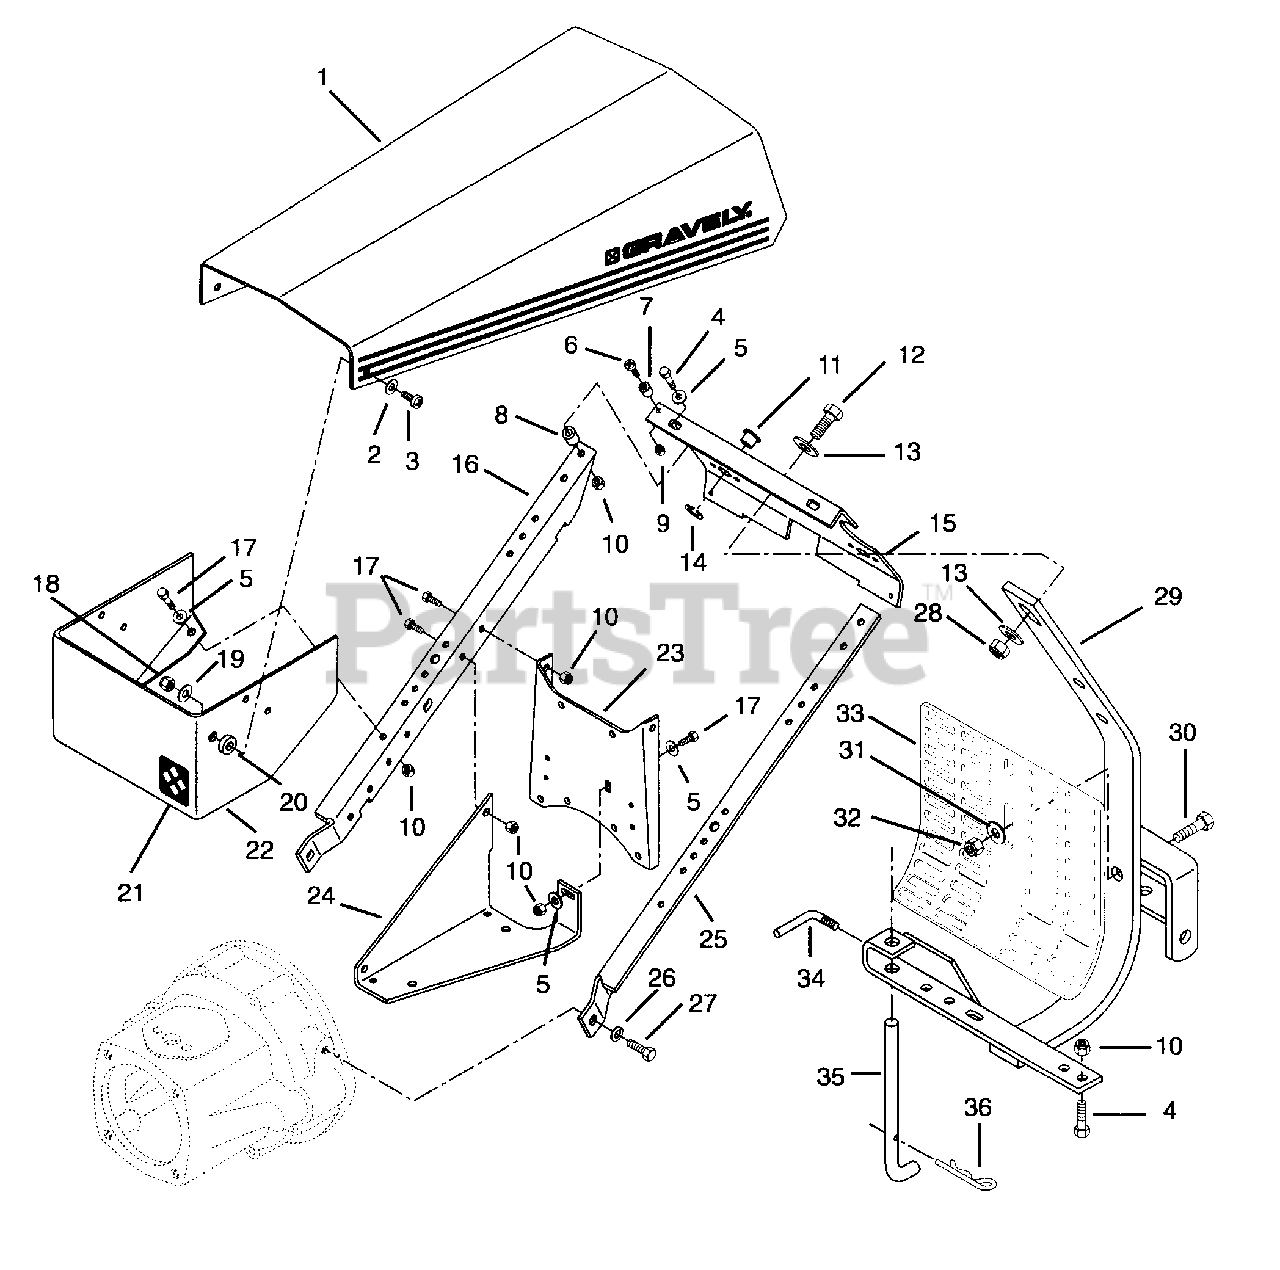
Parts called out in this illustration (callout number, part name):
1	Hood with Decal
1	Hood 8HP
2	Washer-Flat-Steel .281 x .620 x .065
3	Screw-Machine .250-20 x 1
4	Bolt-Hex .38-16 x 1.50 Grade 5
5	Washer-Flat-Steel .406 x .812 x .065
6	Screw-Machine 6-32 x .75
8	Bushing
9	Nut-Locking-Nylon 6-32
10	Nut-Locking-Center .375-16 Grade 2
11	Bushing-Flange .515 x .750 x .745 x 1.00
12	Bolt-Hex .625-11 x 2.00
13	Washer-Flat-Steel .656 x 1.31 x .095
14	Ring-Retaining 1.000 x .748
15	Plate, Silk Screen, Man
15	Plate, Silk Screen
16	Support, Handle Bar Right Hand
17	Bolt-Hex .380-16 x .75
18	Nut-Locking-Center .250-20 Grade 2
19	Washer-Flat-Steel .38 x .875 x .083
20	Bushing, Flange 280 x .750 x .318
21	Decal, Comm. Front
22	Support Hood
23	Bracket
24	Tray, Battery
25	Support, Handle Bar Left Hand
26	Washer-Lock .50 x .125 Reg.
27	Bolt-Hex .50-13 x 1 Grade 5
28	Nut-Locking-Center .625-11 Grade 2
29	Weldment, Hitch 8 HP
30	Bolt-Hex .50-13 x 1.50 Grade 5
31	Washer-Flat-Steel .536 x 1.38 x .109
32	Nut-Locking-Center .50-13 Grade 5
33	Guard, Engine
34	Handle, Adjusting
35	Stand, Kick
36	Pin-Hair-Internal .15 x 2.937
